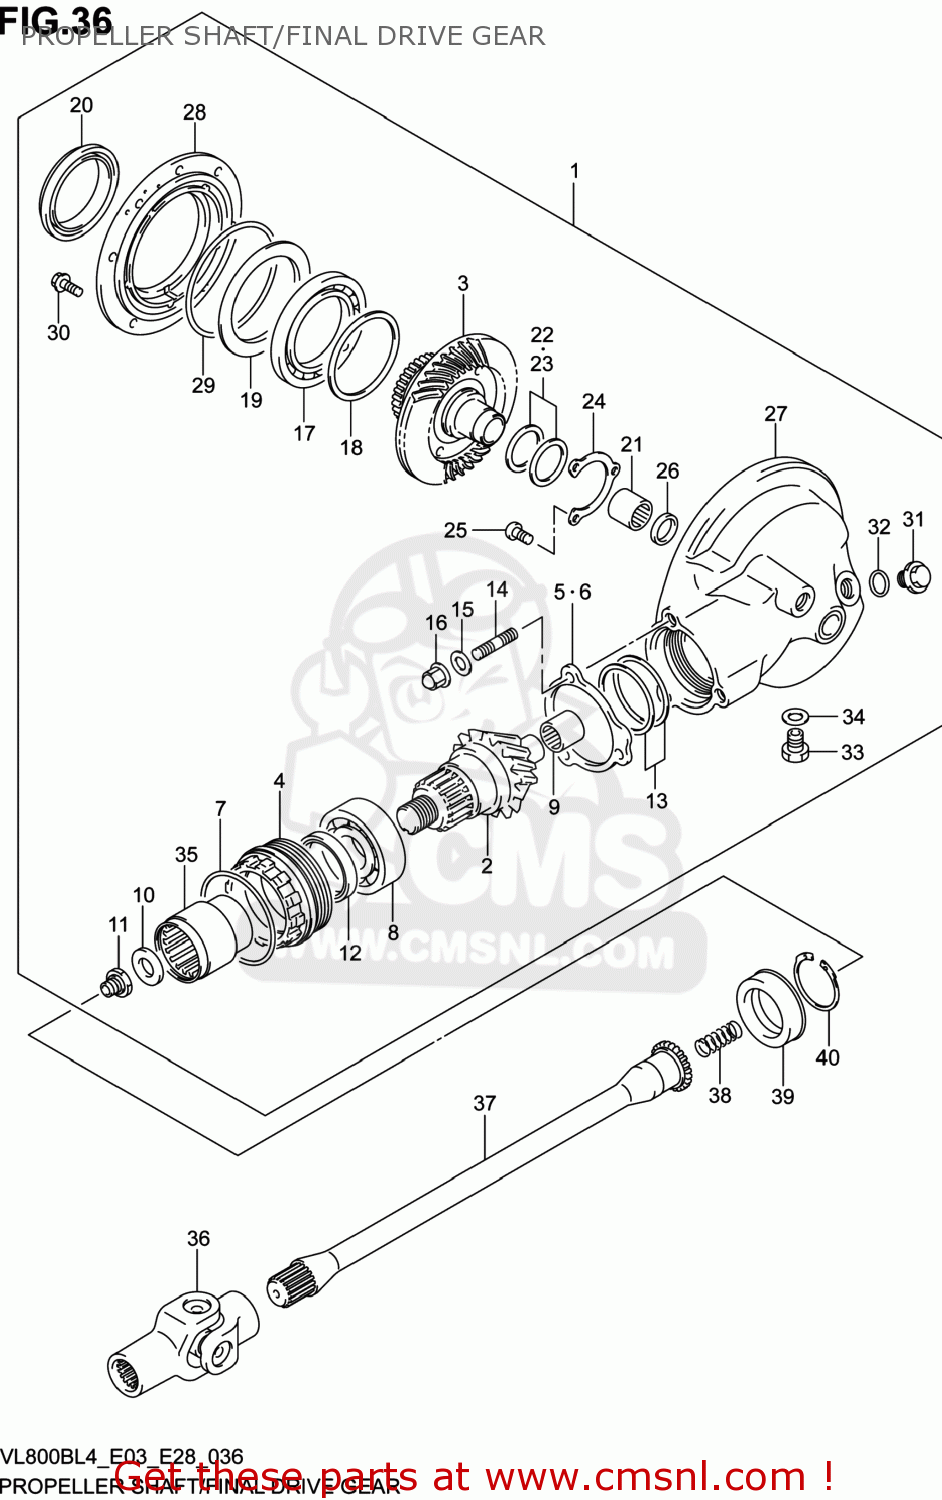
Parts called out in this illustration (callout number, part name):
1	GEAR & CASE SET,FINAL BEVEL
2	GEAR,FINAL DRIVE BEVEL(NT:11)
3	GEAR,FINAL DRIVEN BEVEL(NT:34)
4	STOPPER,FINAL DRIVE BEARING
5	PLATE,BEARING STOPPER
6	PLATE,BEARING STOPPER
7	O RING(D:1.9,ID:61.6)
8	BEARING(30X62X23.8)
9	BEARING(17X32X16)
10	WASHER(16X29X4)
11	NUT
12	SEAL,OIL(38X54X6)
13	SHIM SET,FINAL DRIVE GEAR
14	BOLT,STUD
15	WASHER
16	NUT
17	BEARING(70X110X13)
18	SHIM SET,DRIVEN GEAR BEARING
19	PLATE,FINAL DRIVEN BRG OIL
20	SEAL,OIL(70X96X16)
21	BEARING(32X46X17.7)
22	SHIM SET,FINAL DRIVEN GEAR
23	SHIM SET,FINAL DRIVE GEAR
24	RETAINER,FINAL DRIVEN GEAR BRG
25	SCREW(6X12)
26	SEAL,OIL(30X42X7)
27	CASE,FINAL GEAR
28	CASE,FINAL GEAR BEARING
29	O RING(D:3.5,ID:131.6)
30	BOLT
31	PLUG
32	O RING(D:2.4,ID:17.8)
33	PLUG(MAGNETO)
34	GASKET(13.8X18.8X4.8) (NAS)
35	COUPLING,FINAL DRIVE GEAR
36	YOKE,UNIVERSAL JOINT
37	SHAFT,PROPELLER
38	SPRING
39	SEAL,OIL(28.4X48X15)
40	CIRCLIP
